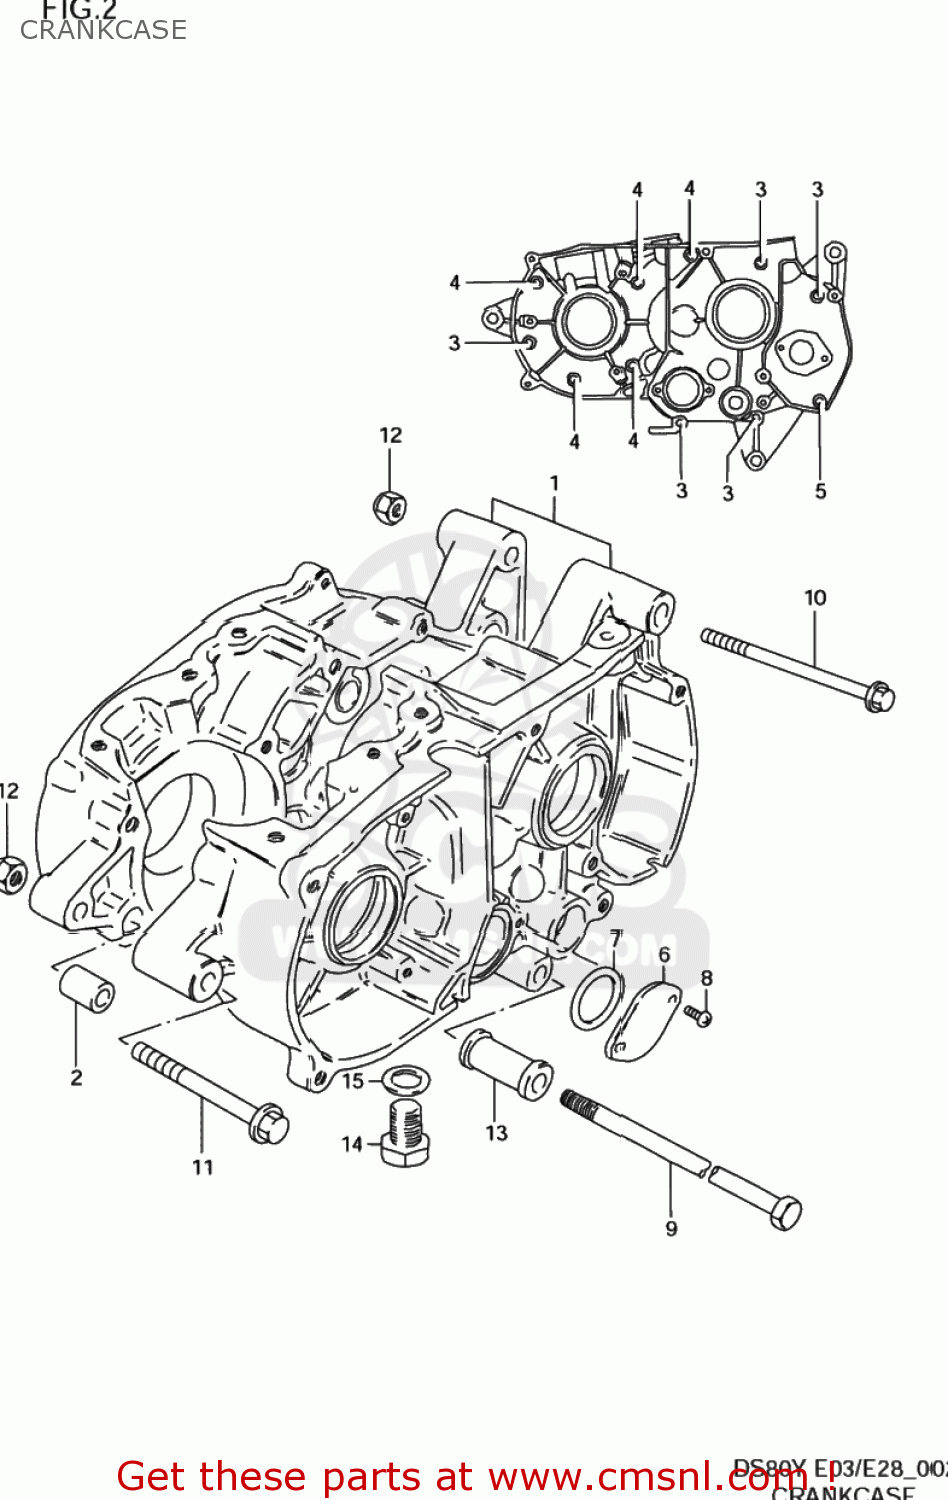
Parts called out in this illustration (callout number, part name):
1	CRANKCASE ASSEMBLY
2	PIN
3	SCREW
4	SCREW
5	SCREW
6	CAP,GEAR SHIFT CAM PIVOT
7	O-RING (D:2.4 ID:26.2)
8	SCREW
9	BOLT(8X230)
10	BOLT(8X100)
11	BOLT(8X70)
12	NUT
13	SPACER,ENGINE MOUNT(L:46)
14	BOLT
15	GASKET(10X14X3.6) (NAS)
